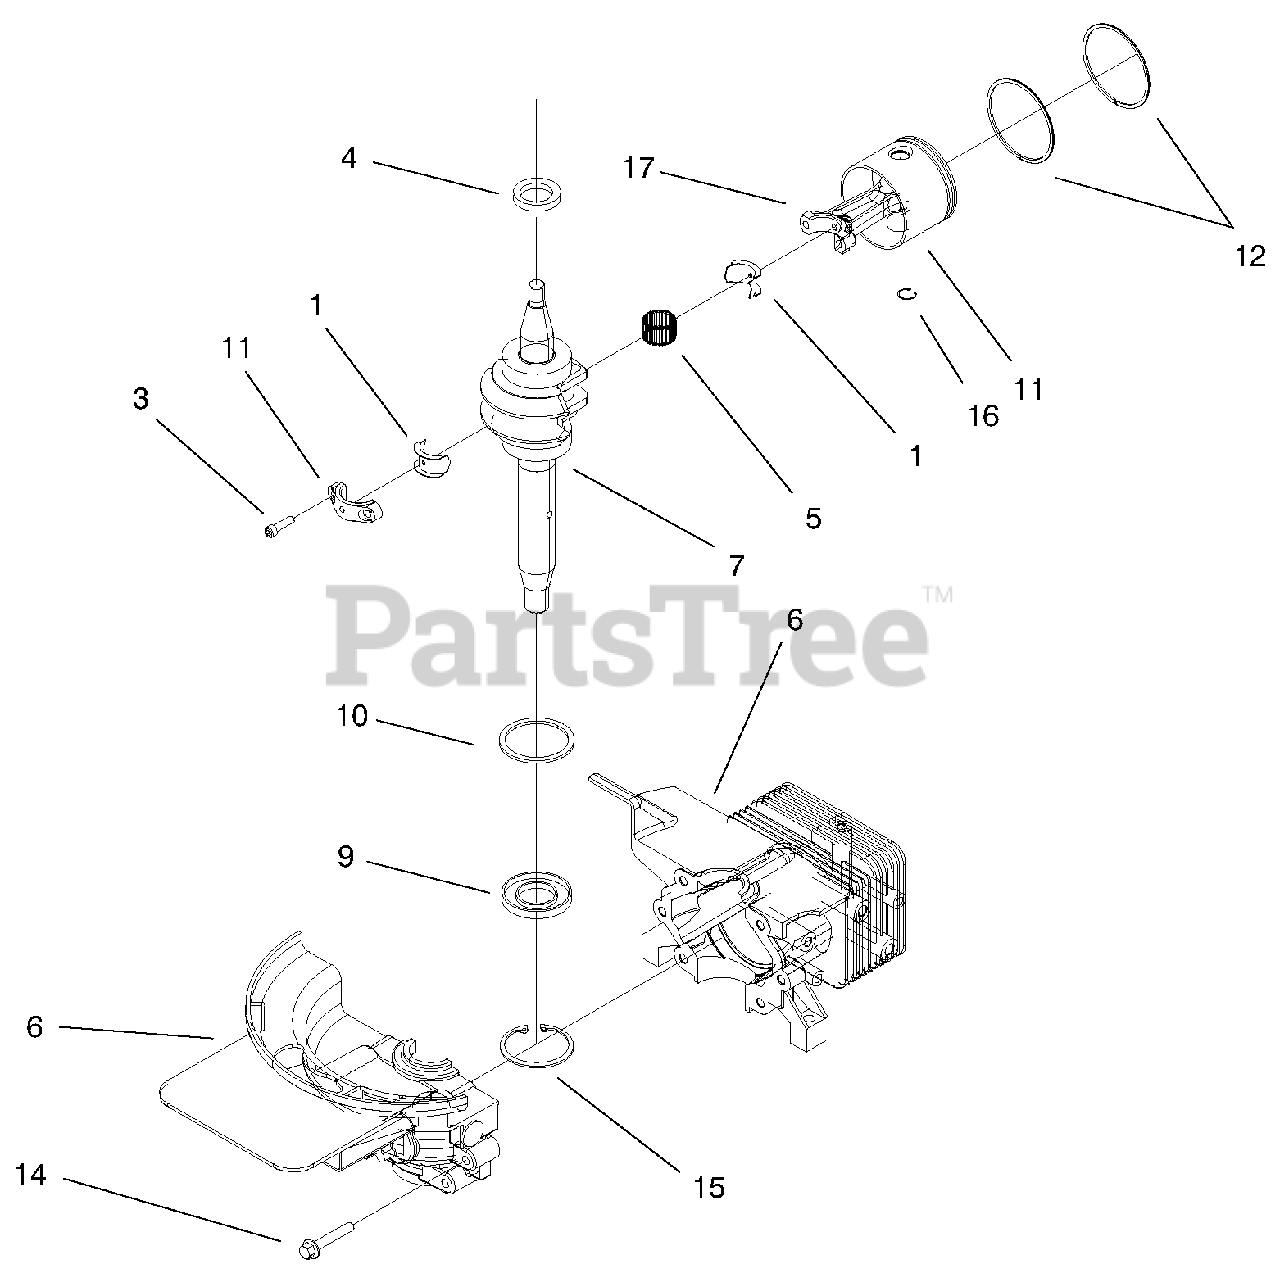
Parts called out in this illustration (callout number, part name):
1	Liner ASM
4	Oil Seal
5	Needle Bearing
6	Cylinder & Crankcase ASM
7	Crankshaft & Bearing ASM
9	Oil Seal
10	Ring Retaining
11	Piston & Conn Rod ASM
12	Ring Set
14	Screw-HWH
15	Ring-Retaining
16	Retaining Ring
17	Connecting Rod ASM
